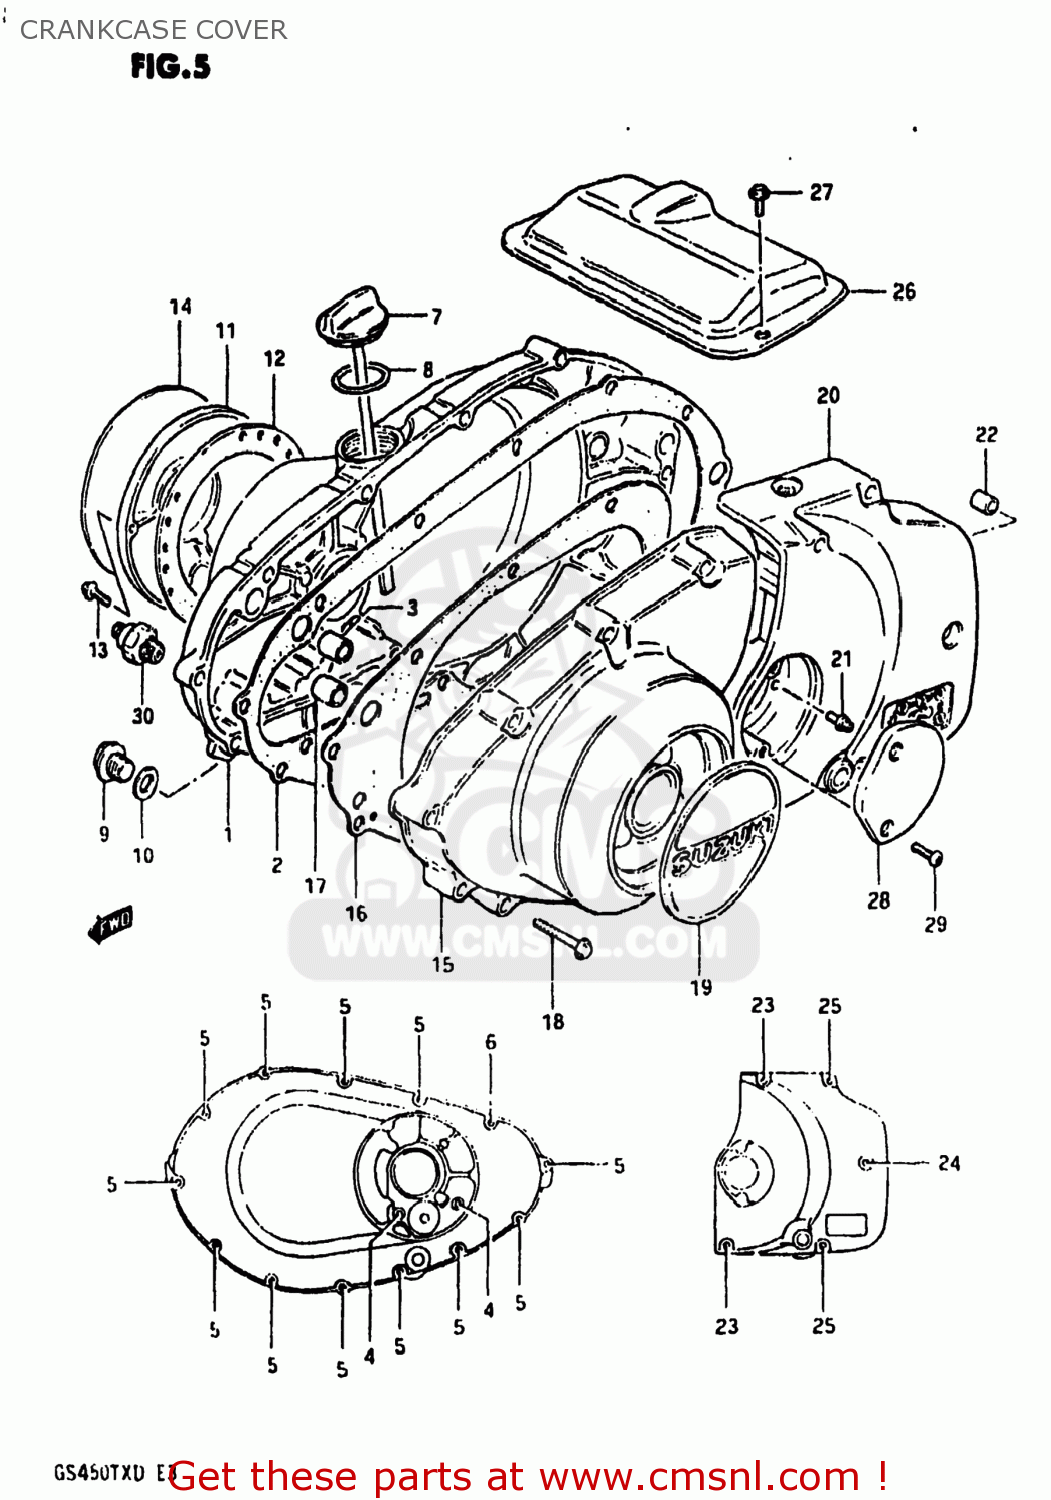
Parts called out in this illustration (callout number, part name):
1	COVER,CLUTCH
2	GASKET,CLUTCH COVER (MCA)
3	PIN
4	BOLT (6X55)
5	BOLT (6X35)
6	BOLT
7	GAUGE,OIL LEVEL
8	O-RING
9	PLUG (14X12)
10	GASKET(14X19.2X2) (NAS)
11	COVER,CONTACT BREAKER
12	GASKET,CONTACT BREAKER COVER (NAS)
13	BOLT 5X16
14	EMBLEM,MAGNETO COVER
15	COVER,MAGNETO
16	GASKET,MAGNETO COVER (MCA)
17	PIN
18	BOLT (6X35)
19	EMBLEM,MAGNETO COVER
20	COVER,ENGINE SPROCKET
21	NIPPLE
22	PIN
23	BOLT (6X65)
24	BOLT (6X50)
25	BOLT (6X40)
26	COVER,STARTER MOTOR
27	BOLT
28	CAP,CLUTCH RELEASE ADJUST
29	SCREW 5X12
30	SWITCH ASSEMBLY
